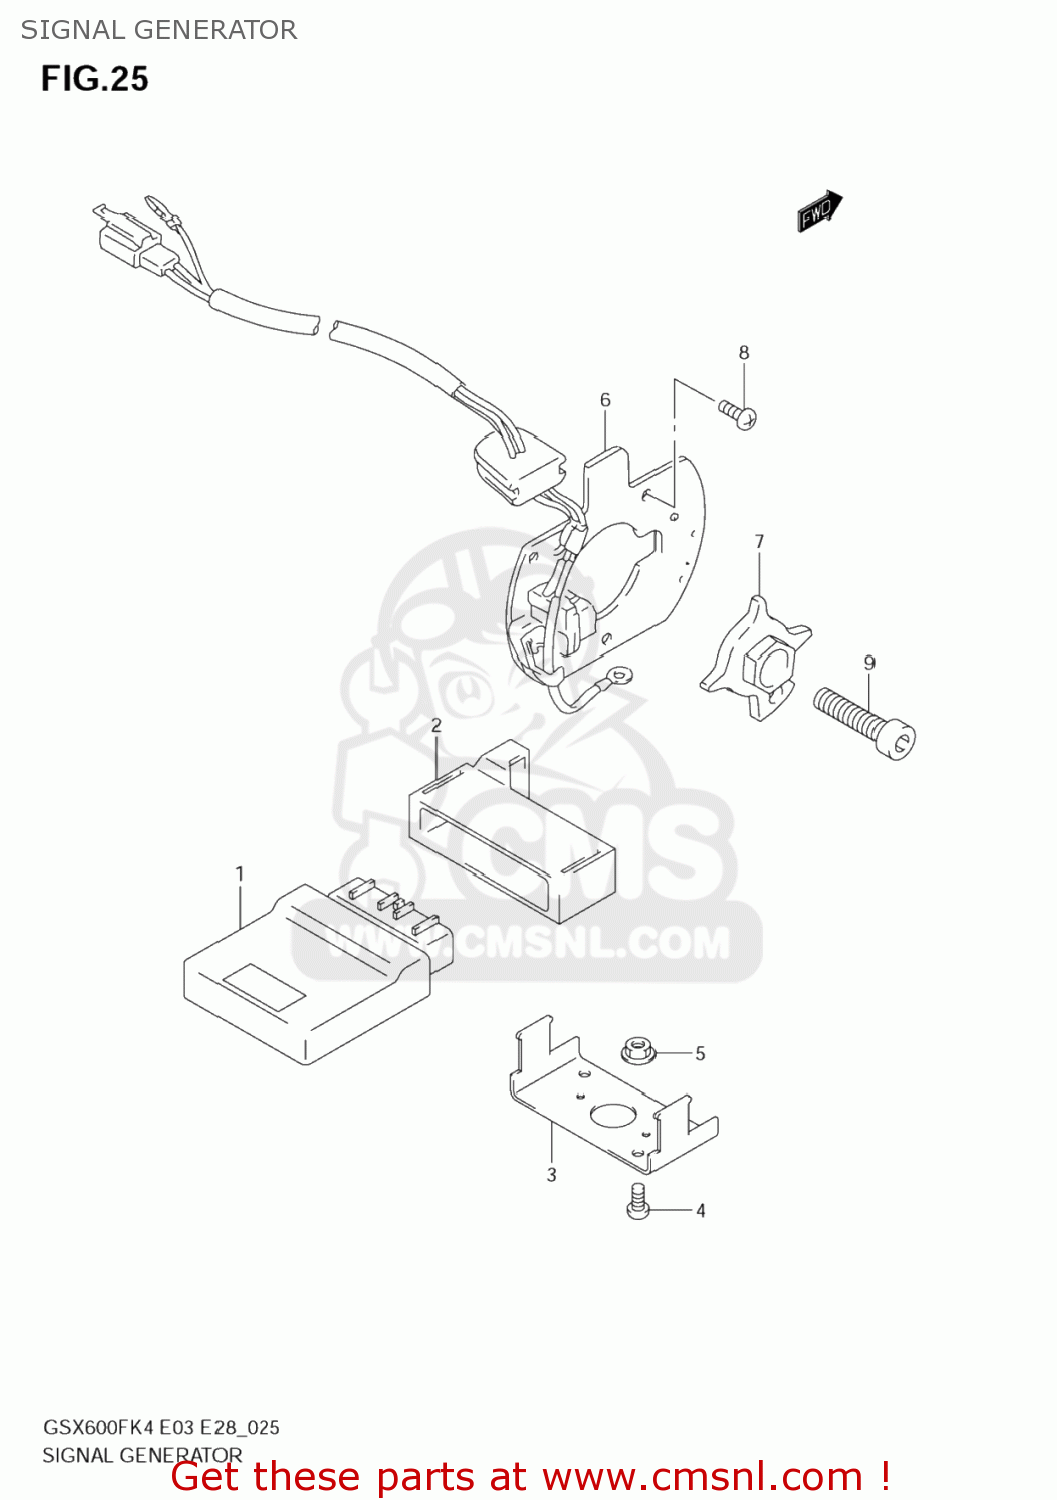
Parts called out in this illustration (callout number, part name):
1	IGNITOR ASSY
2	COVER,IGNITOR
3	BRACKET,IGNITOR
4	SCREW 5X12
5	NUT
6	STATOR,SIGNAL GENERATOR
7	ROTOR,SIGNAL GENERATOR
8	SCREW
9	BOLT
